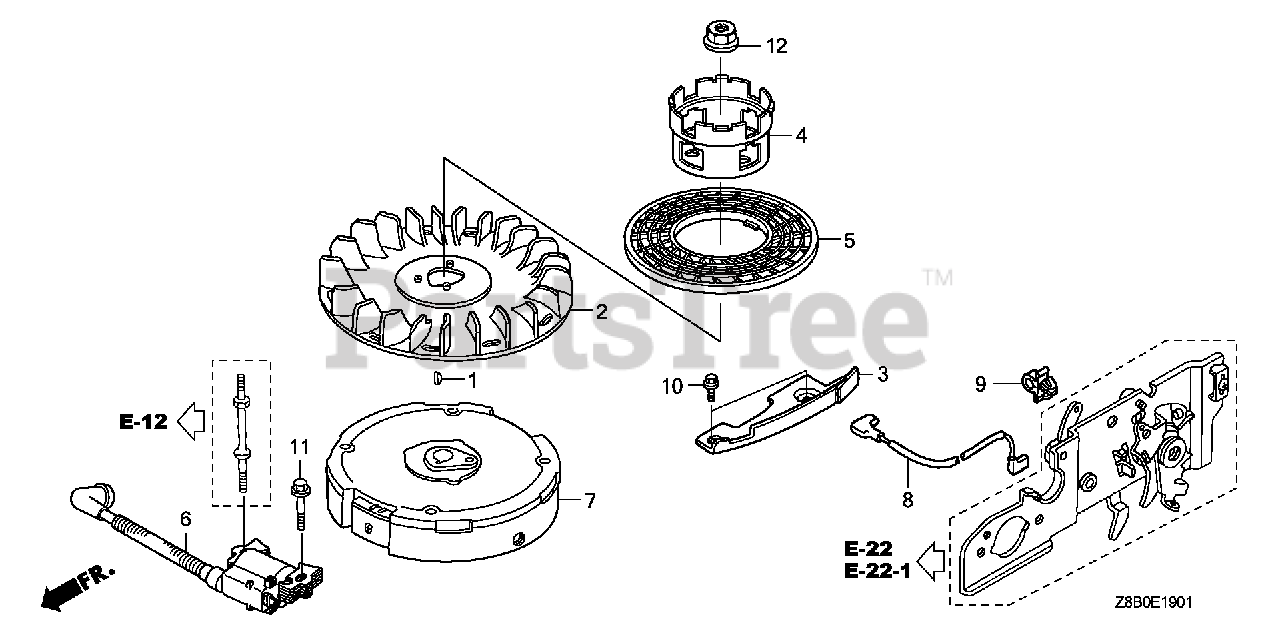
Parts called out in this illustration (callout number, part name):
1	KEY, SPECIAL WOODRUFF (25X18)
2	FAN, COOLING
3	PLATE, SIDE
4	PULLEY, STARTER
5	GRID, SCREEN
6	COIL ASSY., IGNITION (TOYO)
7	FLYWHEEL
9	HOLDER, WIRE (FASTEX)
9	CLIP A, CABLE (3.8MM BLACK) (NIFCO)
10	BOLT, FLANGE (6X12) (CT200)
11	BOLT, FLANGE (6X23) (CT200)
12	NUT, SPECIAL (14MM)
